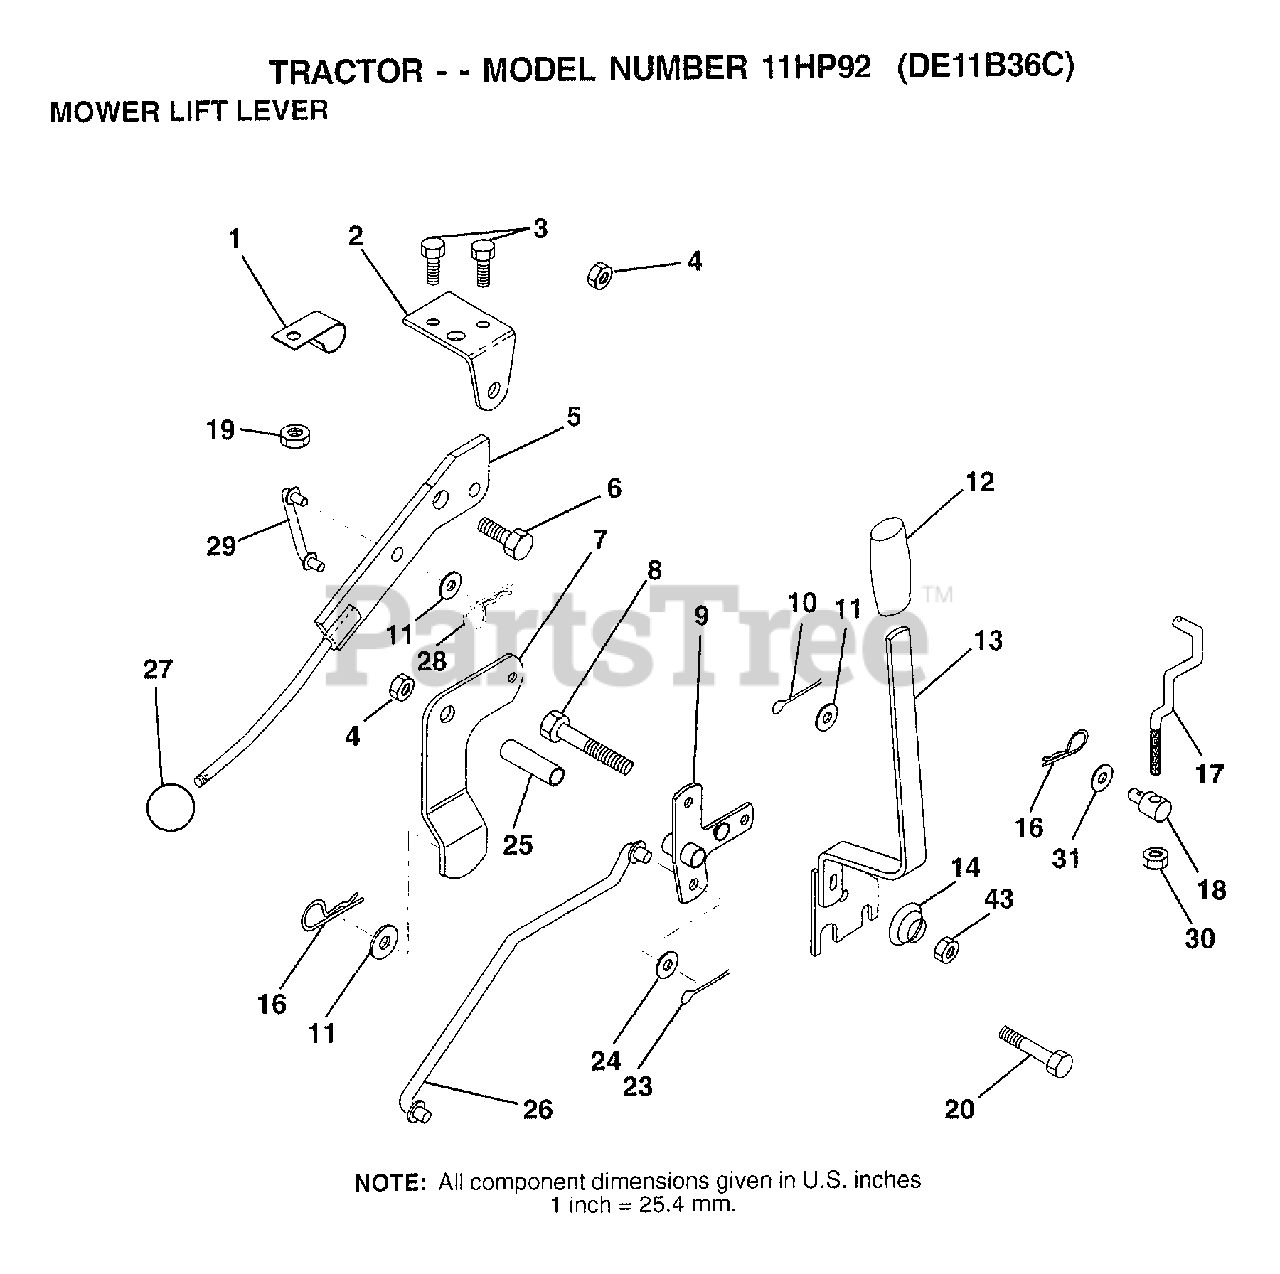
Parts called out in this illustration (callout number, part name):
1	"CLIP,INSULATOR"
2	BRKT CLUTCH
3	BOLT HXHD FIN
5	LEVER.ASM.CLUTCH
6	"BOLT, SHOULDER LT"
7	MWR CLUTCH ARM AS
8	BOLT
9	"BELLCRANK,LIFT"
10	COTTER PIN
11	WASHER
13	HANDLE.ASM.LIFT
14	SPRING COMPRESSIO
16	SPRING.RETAINER
17	"LINK,LIFT FRT"
18	TRUNION ADJ
20	BOLT
23	PIN COTTER 1/8
25	TUBE SPACER
26	ROD LIFT MOWER
27	KNOB T(3/8 HOLE)
28	RETAINER M
29	CLUTCH LINK
30	NUT
31	WASHER
